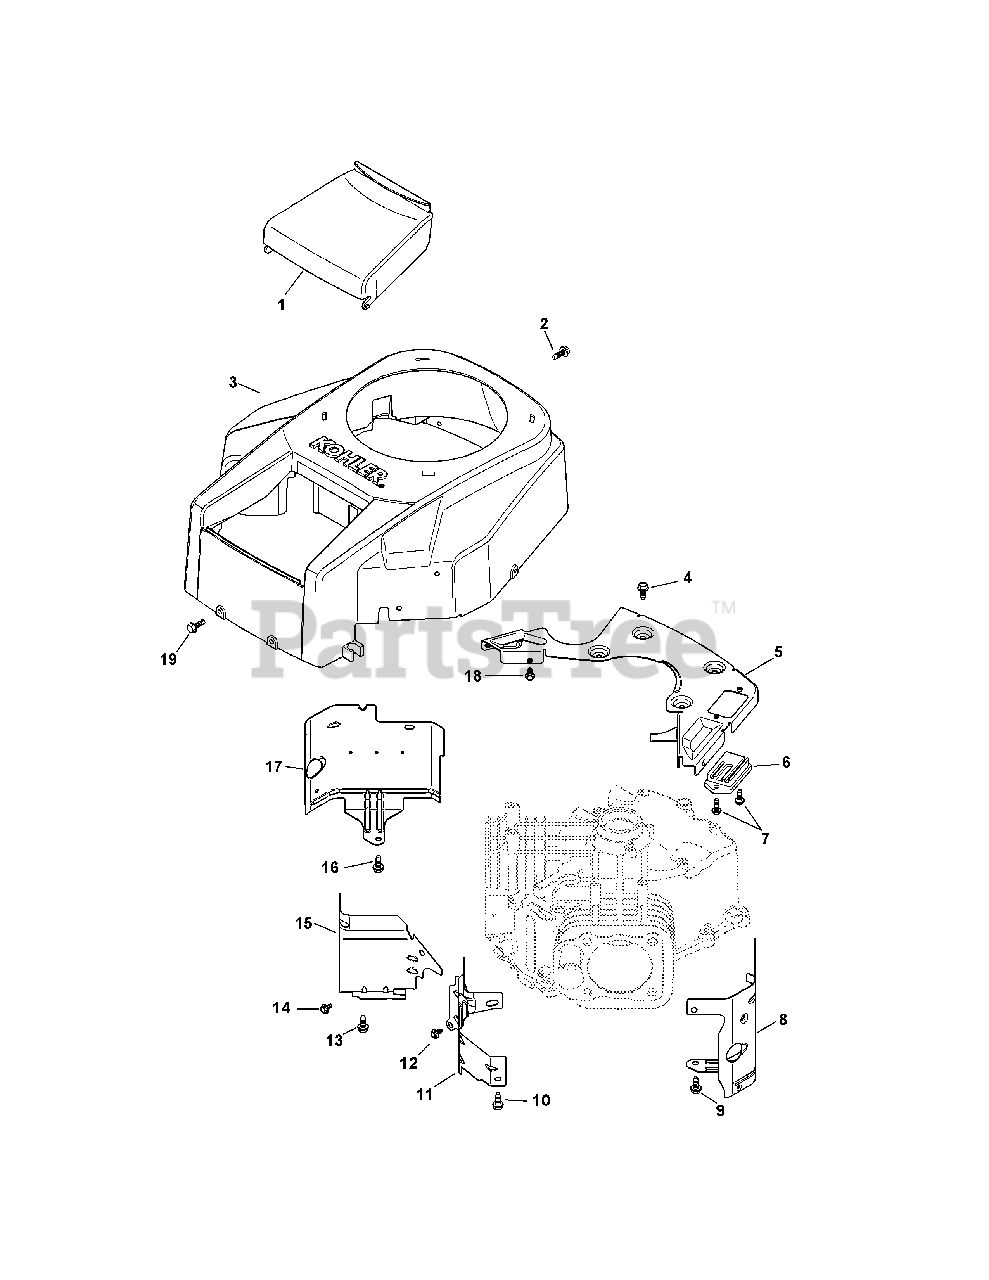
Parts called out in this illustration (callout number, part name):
1	Cover, Air Cleaner
2	Screw, Flg Thd Frm M5X0.8X16
3	Kit, Housing Blower
4	Screw, Flg Thd Frm M6X1.0X16
5	Kit, Backing Plate
6	Regulator/Rectifier
7	Screw, Flg Thd Frm M5X0.8X16
8	Baffle, Cyl Barrel - #2 Side
9	Screw, Flng Thd Frm M6X1.0X10
10	Screw, Flg Thd Frm M6X1.0X16
11	Baffle, Valley #2 Cylinder
12	Screw, Flg Thd Frm M5X.8X10
13	Screw, Flg Thd Frm M6X1.0X16
14	Screw, Flg Thd Frm M5X.8X10
15	Baffle, Valley #1 Cylinder
16	Screw, Flng Thd Frm M6X1.0X10
17	Baffle, Cyl Barrel - #1 Side
18	Screw, Flg Thd Frm M5X0.8X16
19	Screw, Tap M6X1.7X18
